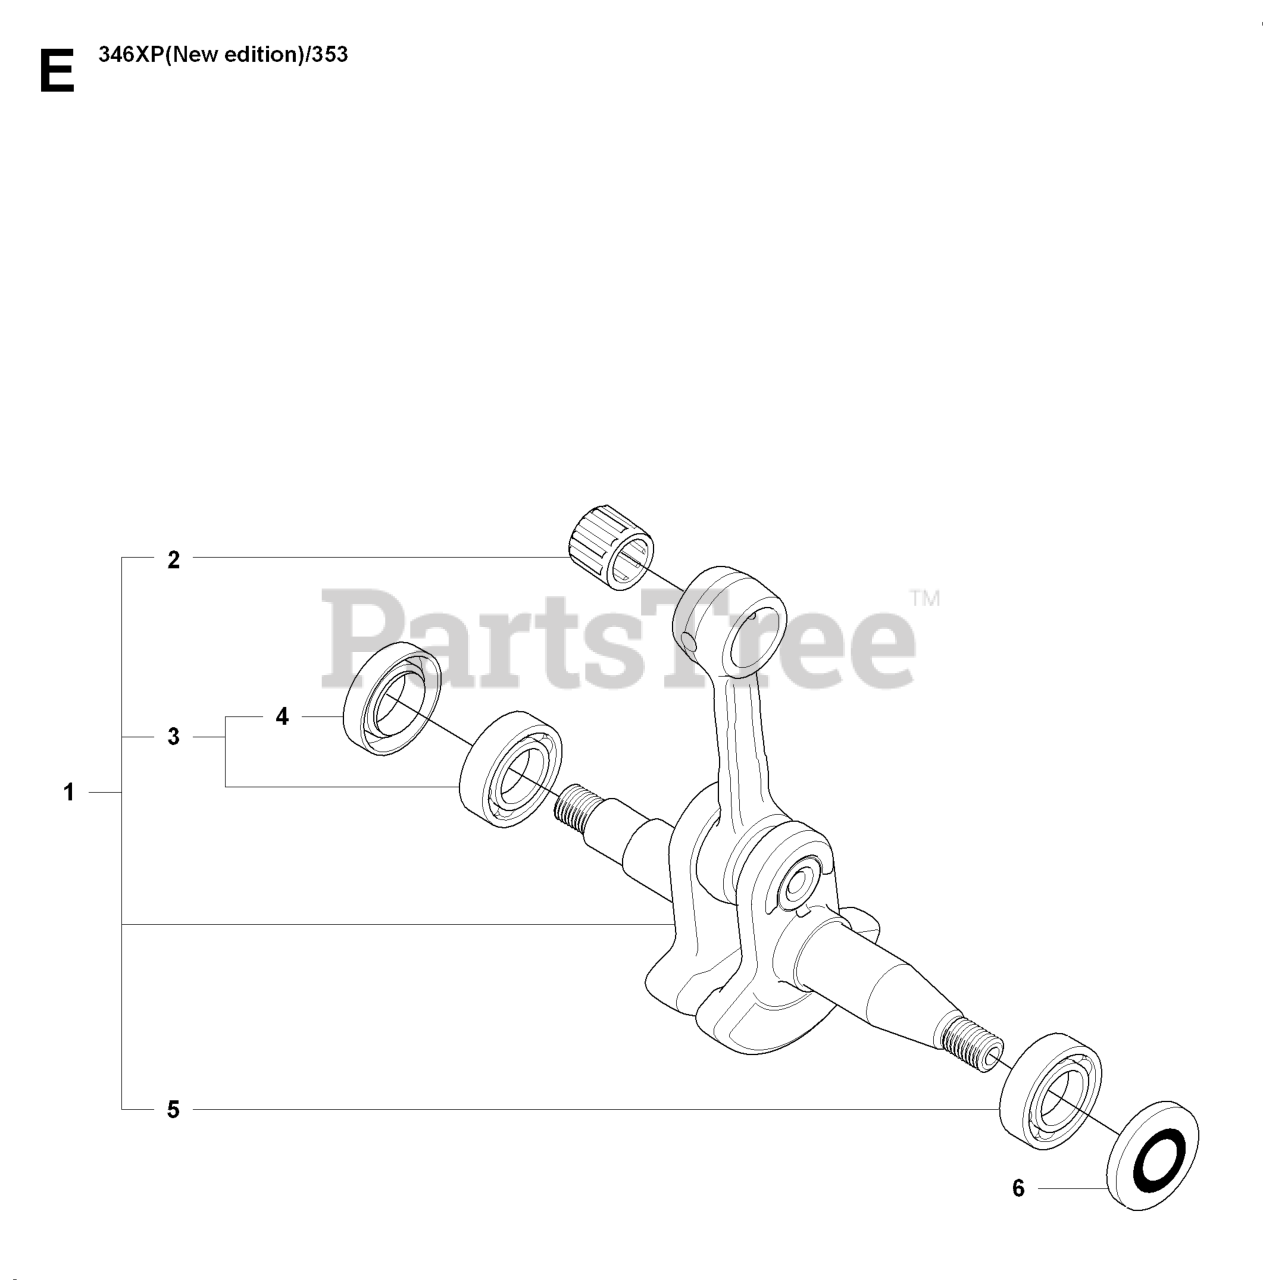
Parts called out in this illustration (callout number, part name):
1	CRANKSHAFT
2	SUPPORT BUSHING
3	%BALL BEARING
4	RADIAL SEAL
5	BALL BEARING-6202-C3 SKF
